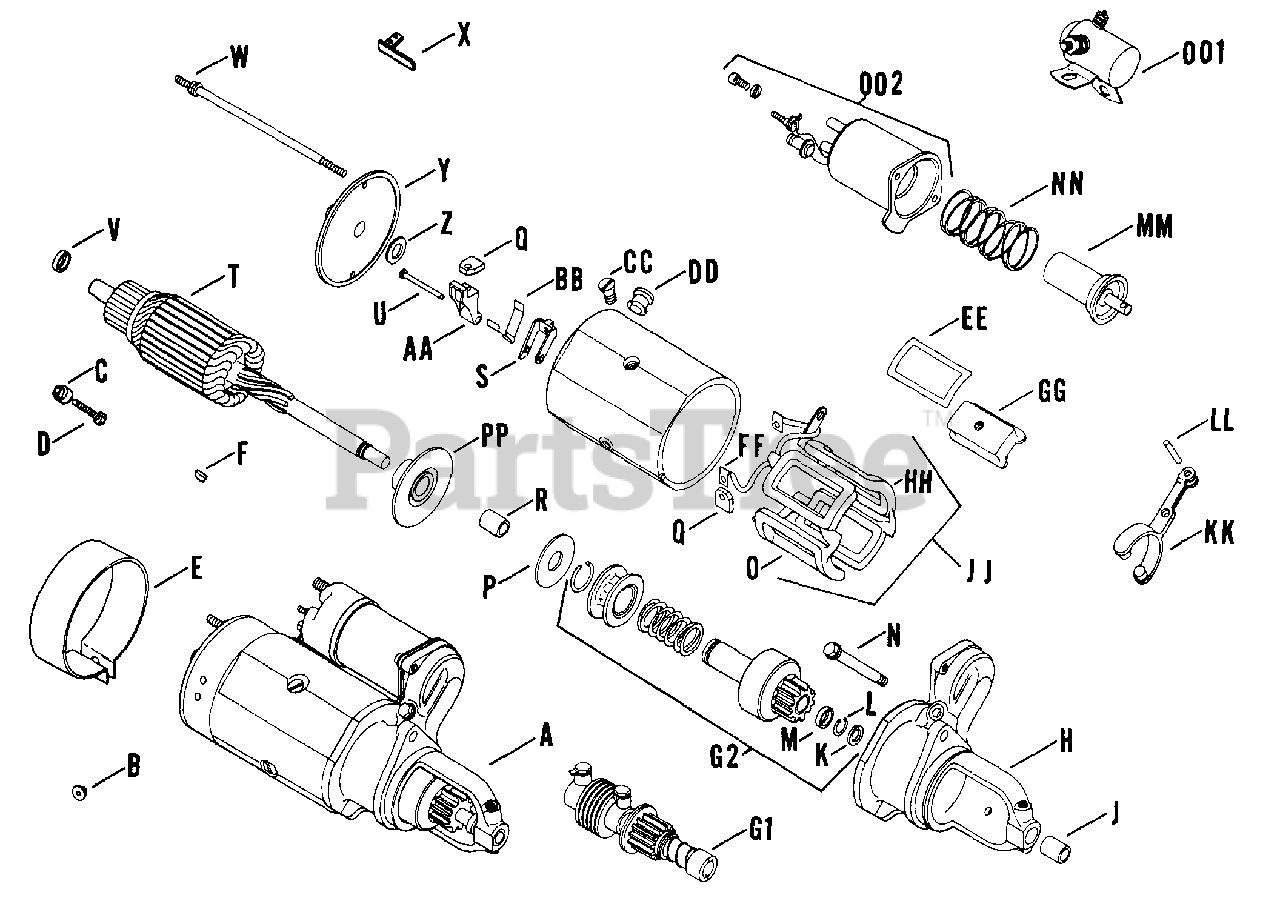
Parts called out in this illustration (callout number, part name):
E	Cover, band (Discontinued--Not Available)
K	Washer, space D.E.
U	Pin, brush holder hinge (Insulated)
U	Pin, brush holder stop (Insulated)
Z	Washer, space C.E.
CC	Screw, pole shoe
